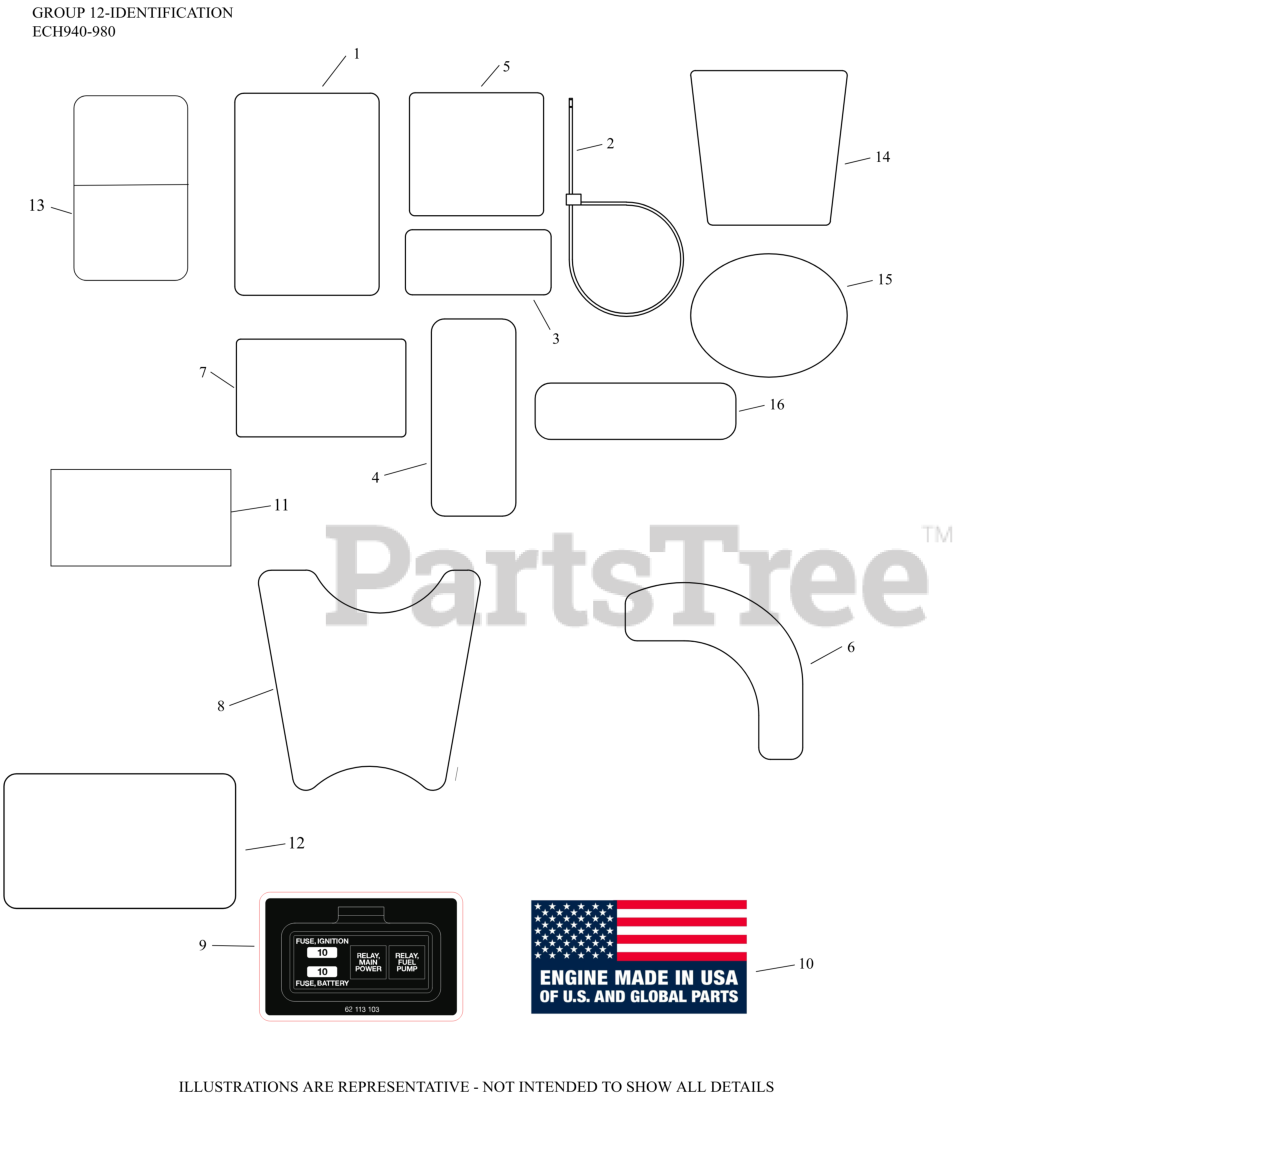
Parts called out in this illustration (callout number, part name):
1	LABEL, CLEAR LAMINATION
3	LABEL, EFI FUEL FILTER
4	LABEL, CANADIAN COMPLIANCE
5	DECAL, HORSEPOWER & DISPLACEMENT
6	LABEL, KEY SWITCH
7	LABEL, THROTTLE
8	LABEL, WARNING LIGHT
9	DECAL - DISCONTINUED
